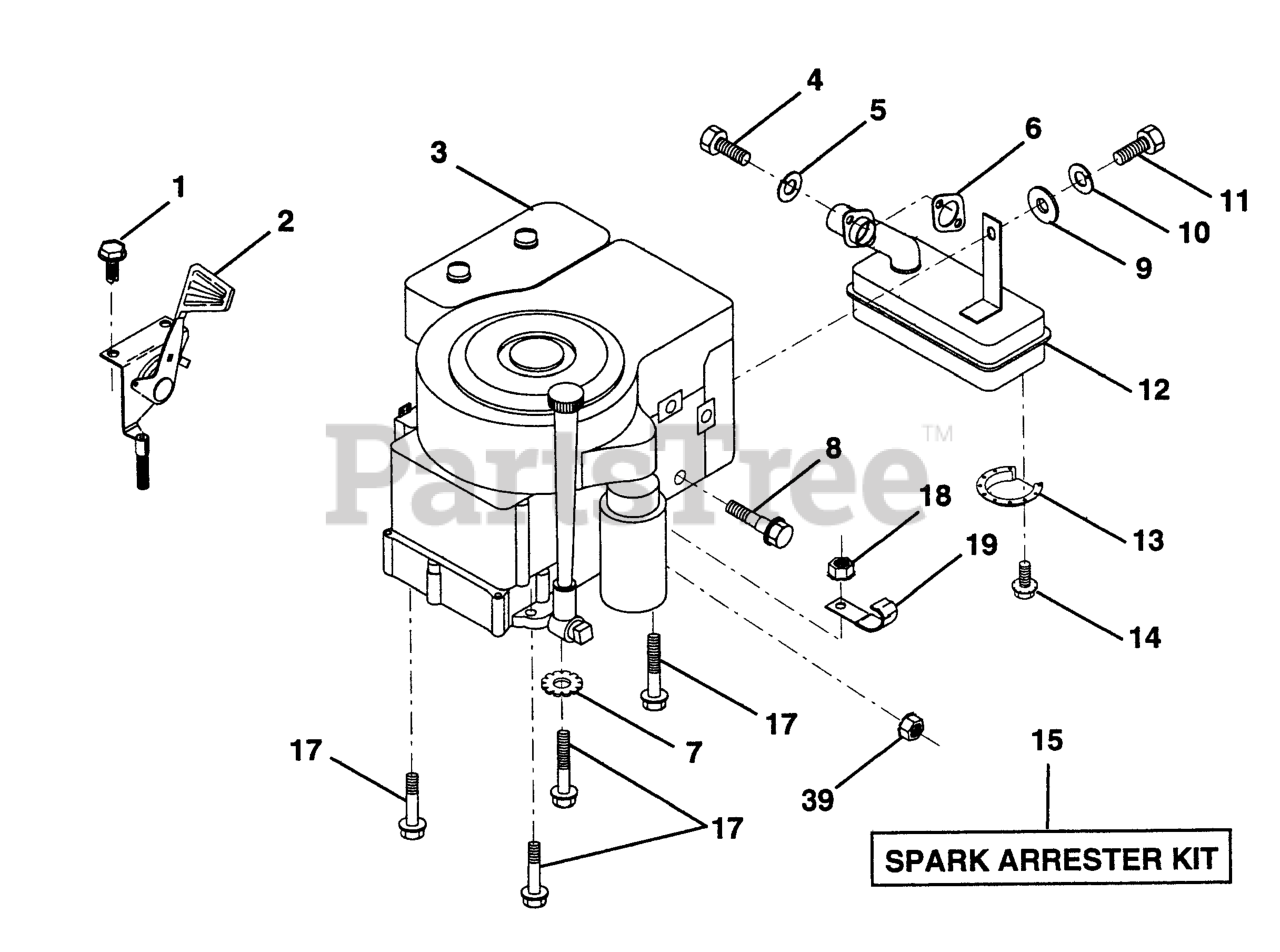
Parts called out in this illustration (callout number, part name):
2	CONTROL.TH/CH.RH.BLK.FLG.26
3	Engine
4	SCREW
5	WASHER.LOCK.HVY.HLCL.SPR.5/16
6	GASKET.ENG.1.313 ID.TIN PLATED
7	LOCKWASHER
9	WASHER
10	LOCKWASHER
11	Bolt, Hex, Fin.
12	MUFFLER.SINGLE.B&S.12HP
13	DEFL MUFFLER LTV
14	SCREW
15	KIT.SPARK ARRESTOR 794945 B&S
17	SCREW LT
19	CLIP T
39	NUT FLANGE 1/4-20 STARTER NUT
